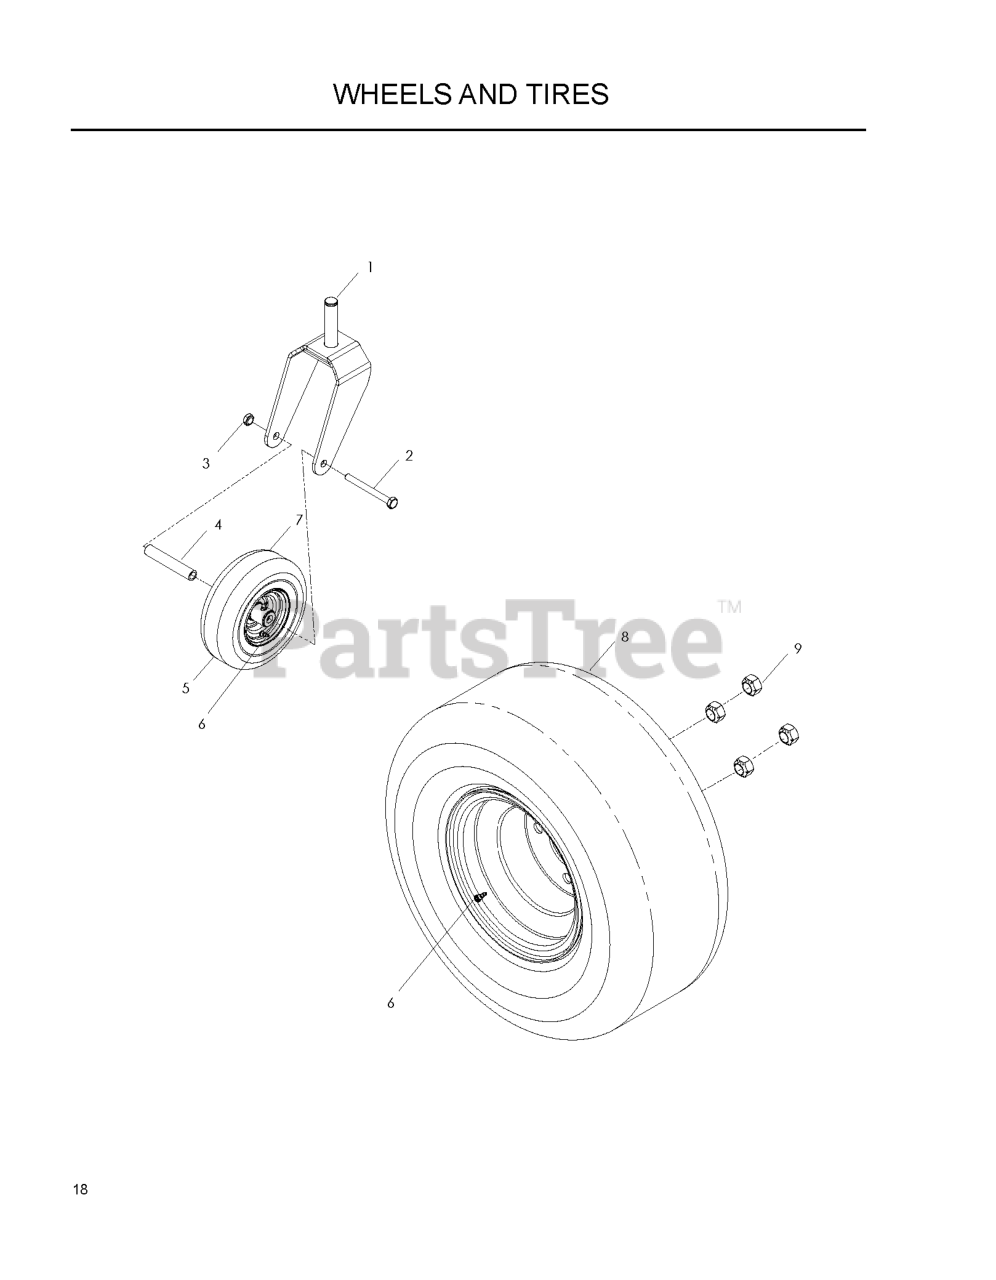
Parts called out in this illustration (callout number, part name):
1	CASTER WLDT
2	HCS 1/2C X 5 1/2
3	NUT 1/2-13 HEX NYLOC ZD
5	TIRE COMPLETE
6	VALVE STEM TR-412
7	TIRE - CASTER
8	TIRE/WHEEL.ASSEM.18X7.5-8.ZTR
9	LUG NUT 1/2F
